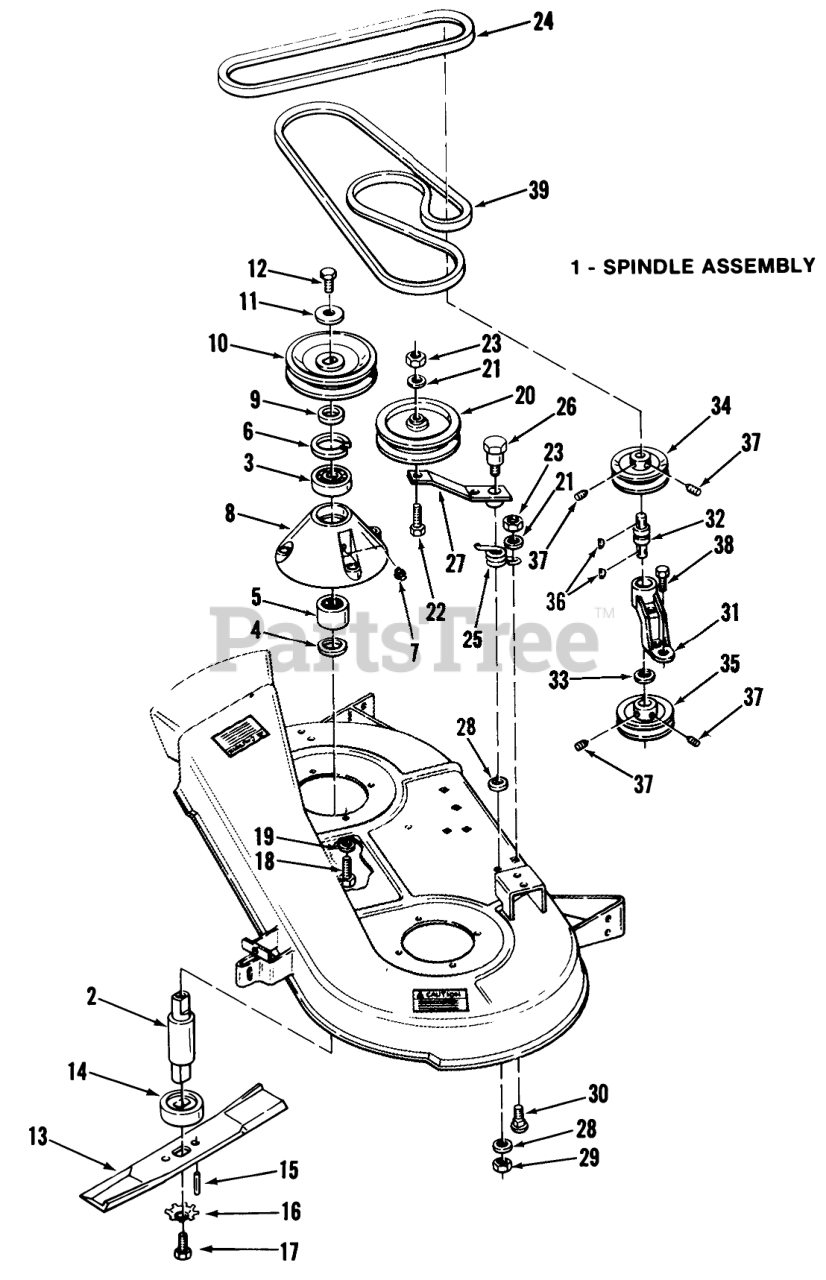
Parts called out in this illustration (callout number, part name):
1	Spindle Assembly (Includes Items 2 Thru 8)
2	SPINDLE MOWER
3	BEARING-BALL
4	OIL SEAL
5	BEARING-NEEDLE
6	INT SNAP RING
7	Fitting-Grease
8	HOUSING
9	SPACER
10	PULLEY-BLADE
11	WASHER
12	Bolt
13	S/A BLADE KIT
14	Spindle Cup
15	SPIROL ROLL PIN
16	WASHER
17	Bolt
18	Bolt
19	LOCKWASHER
20	Idler Pulley
21	Washer
22	Bolt
23	Nut
24	V-BELT
25	SPRING-TORSION
26	BOLT-SHOULDER
27	Idler Arm
28	WASHER
29	Hex Nut 7/16-14
30	Bolt
31	HOUSING DRIVE BRG R
32	BEARING-INT SHAFT
33	Snap Ring
34	PULLEY
35	PULLEY-SPLIT
36	KEY-WOODRUFF
37	Set Screw
38	Bolt
39	BELT-V MOWER
